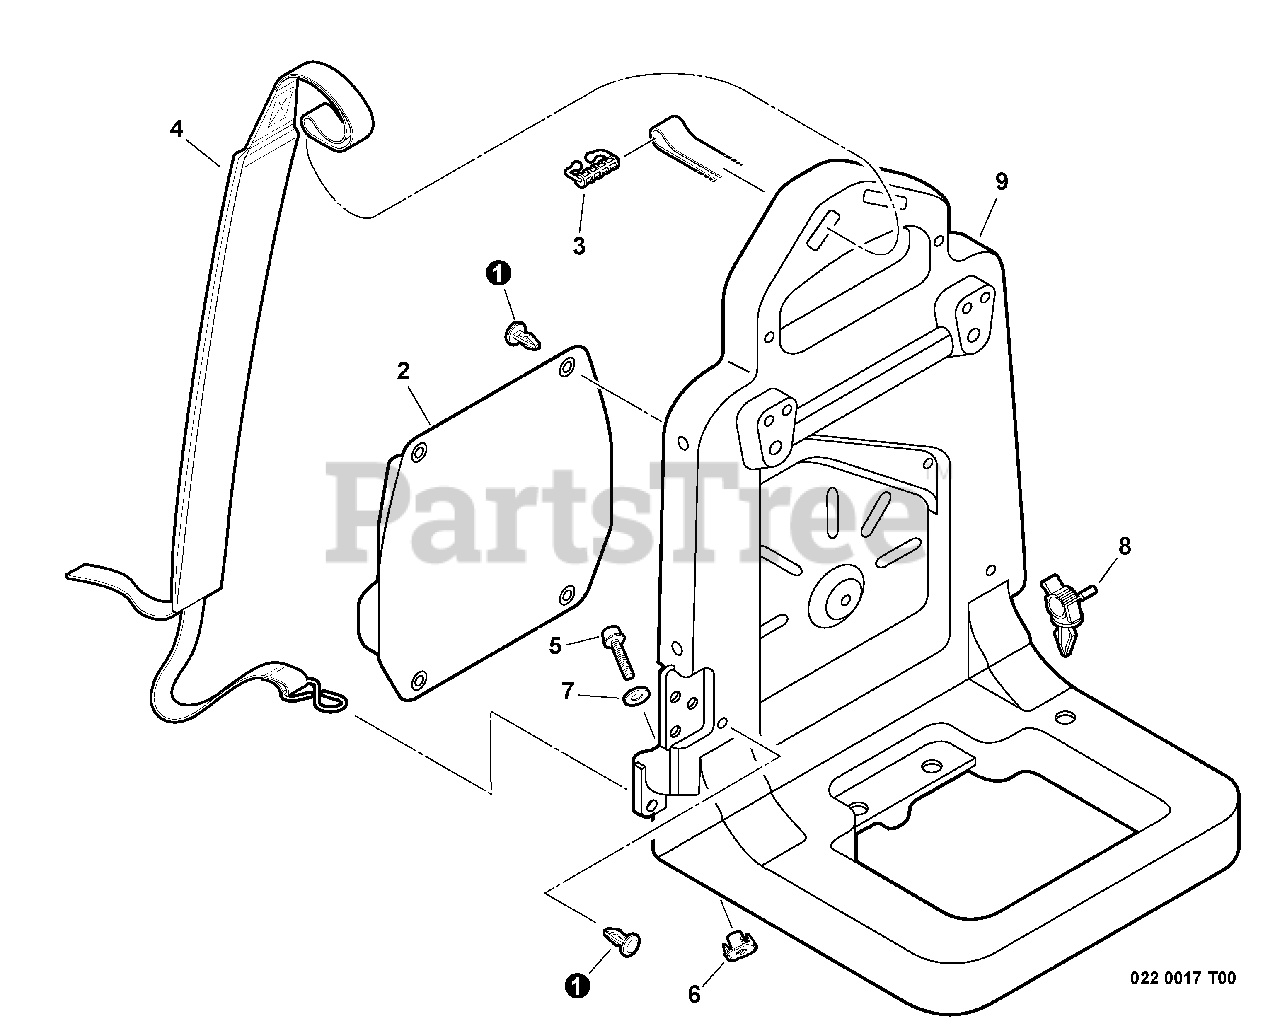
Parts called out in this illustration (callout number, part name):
2	CUSHION, BACKPACK
3	CLIP, HARNESS
4	HARNESS, BACKPACK
5	BOLT 6×25
7	WASHER 6.6×20×1.6
8	CLIP, CABLE
9	FRAME, BACKPACK
